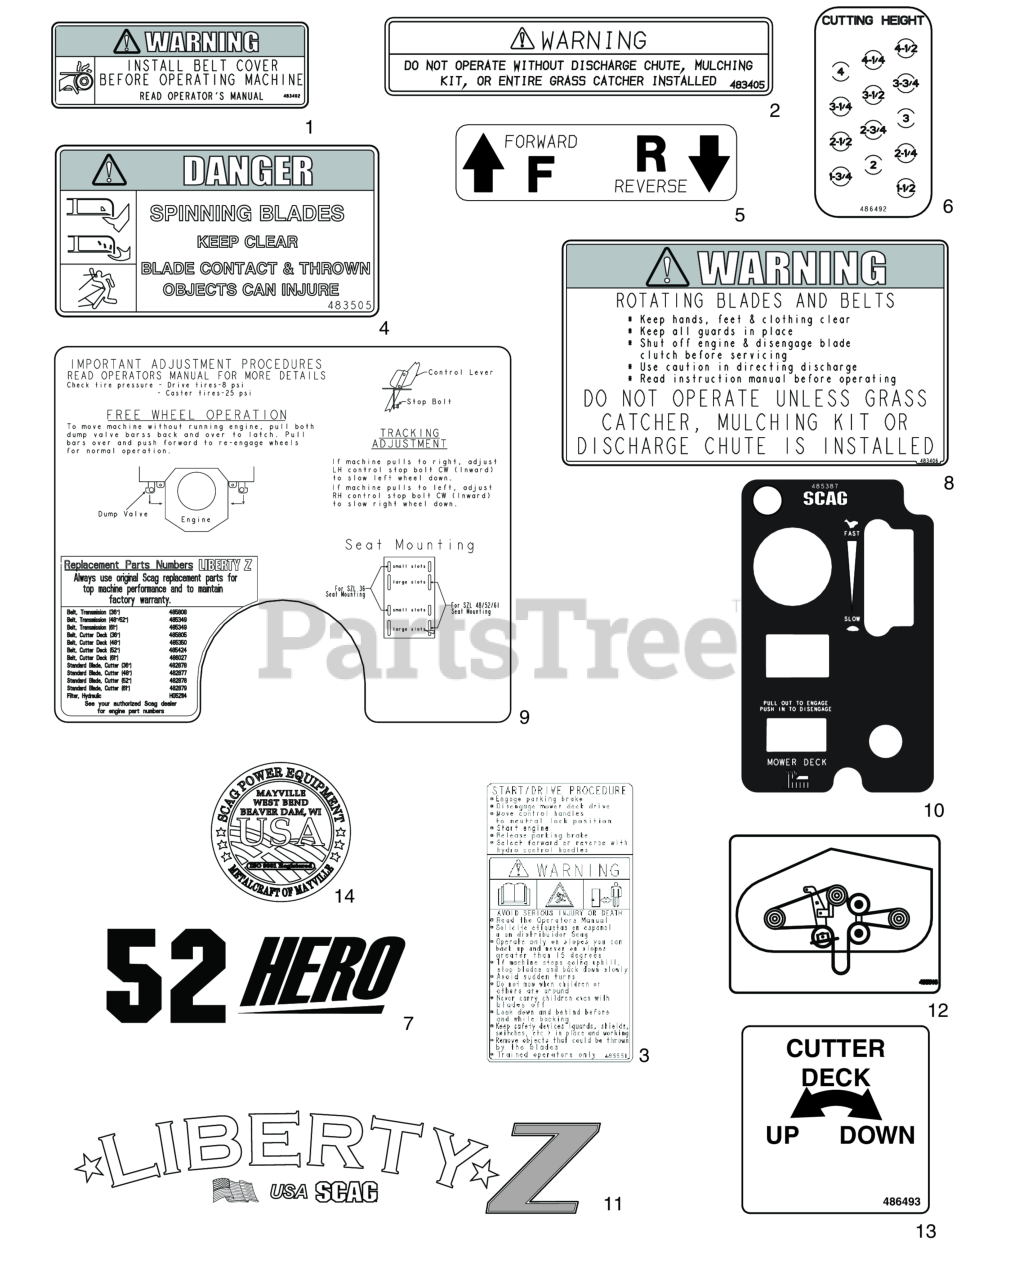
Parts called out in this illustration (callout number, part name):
1	Decal, Warning - Belt Cover
2	Decal, Warning-Discharge
3	Decal, Start/Drive
4	Decal, Spinning Blades
5	Decal, Traction Control
6	Decal, Height of Cut
7	Decal, 48 Hero
8	Decal, Warning - Rotating Blades
9	Decal, Adjustments - SZL
10	Decal, Instrument Panel - SZL (48 & 52)
11	Decal. Liberty Z - Fuel Tank
12	Decal, SZL / SFZ / SPZ Belt Routing
13	Decal, Cutter Deck Lift Control
14	Decal, Metalcraft - USA
